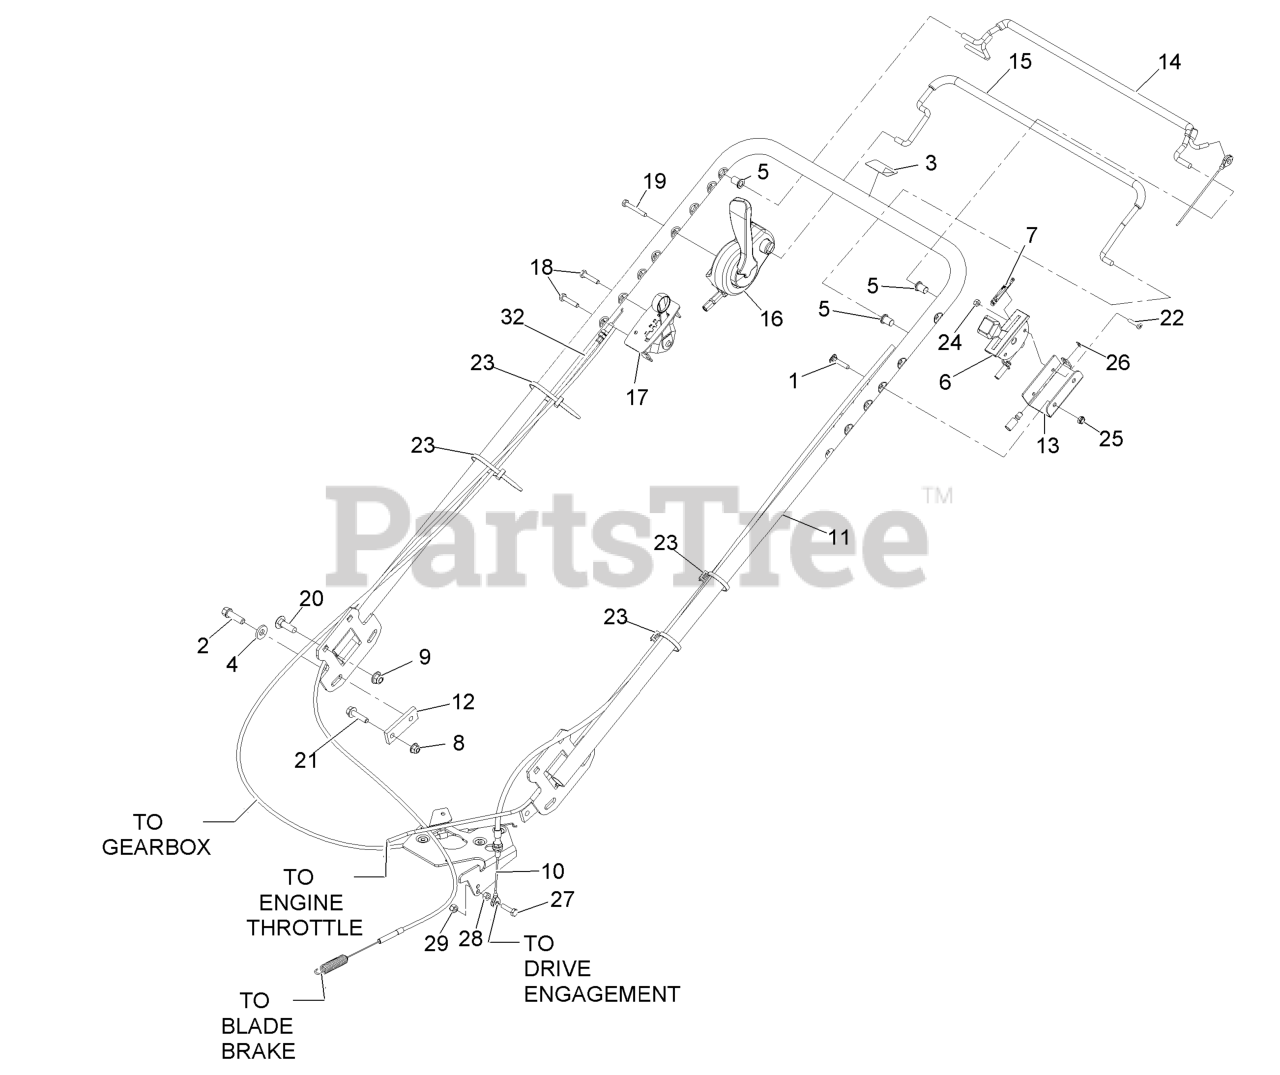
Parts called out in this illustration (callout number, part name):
1	BOLT-HANDLE
2	SCREW-TAPTITE
3	DECAL-PROTECTION, EAR
4	WASHER-BELLEVILLE
5	BUSHING
6	CONTROL-THROTTLE
7	DECAL-THROTTLE / CHOKE
8	NUT-HF, NI
9	NUT-HF, NI
10	CABLE-TRACTION
11	ASM,HANDLE W/DECALS
12	NUT-HANDLE
13	BRACKET-CONTROL
14	BAIL-TRACTION
15	BAIL-BBC (WITH GRIP)
16	CONTROL-BBC
17	CONTROL-SHIFT
18	SCREW-HH
19	SCREW-HH
20	BOLT-CARR
21	SCREW-HHF
22	SCREW-PPH
23	TIE-CABLE
24	NUT-LOCK, NI
25	NUT-LOCK, NI
27	SCREW-HH
28	NUT-HEX
29	NUT-LOCK, NI
32	CABLE-SHIFTER
